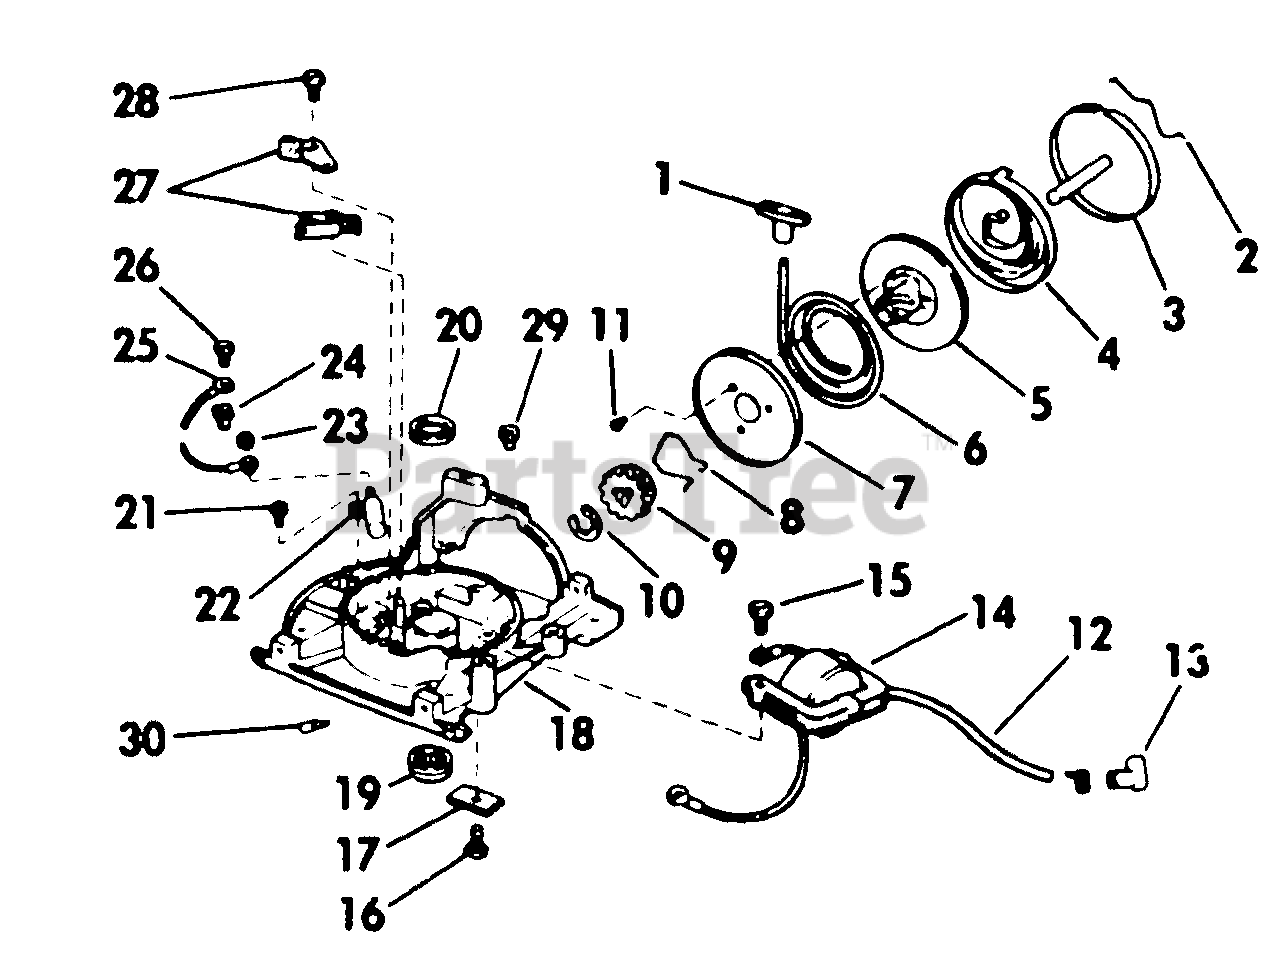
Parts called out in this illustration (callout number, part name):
1	Handle-Starter
2	Spring-Starter Rope Retainer
3	Spring-Cup-Pin Assy.
4	Spring-Starter
5	Pulley-Starter
6	Rope-Starter
7	Plate-Starter Pulley
8	Spring-Starter Pinion
9	Pinion-Starter
10	Retainer-Push-On
11	Screw-Threaded Cutting Starter
12	High Tension Lead Assy.
13	Cover & Tertninal Assy.
14	Coil & lamination Assy.
15	Scr.-Lamination Mtg.
16	Scr.-Starter Attach.
17	Clamp-Starter Pin
18	Arm. Pl., Brg. & Oil Seal Assy.
20	Oil Seal
21	Scr.-Cond. Mtg.
22	Cond. & Nut Assy.
24	Grommet-Nylon
25	Terminal & Lead Assy.
26	Scr.-Shut-Off Sw.
27	Brkr. Base & Arm Assy.
28	Scr.-Breaker Base
29	Grommet
